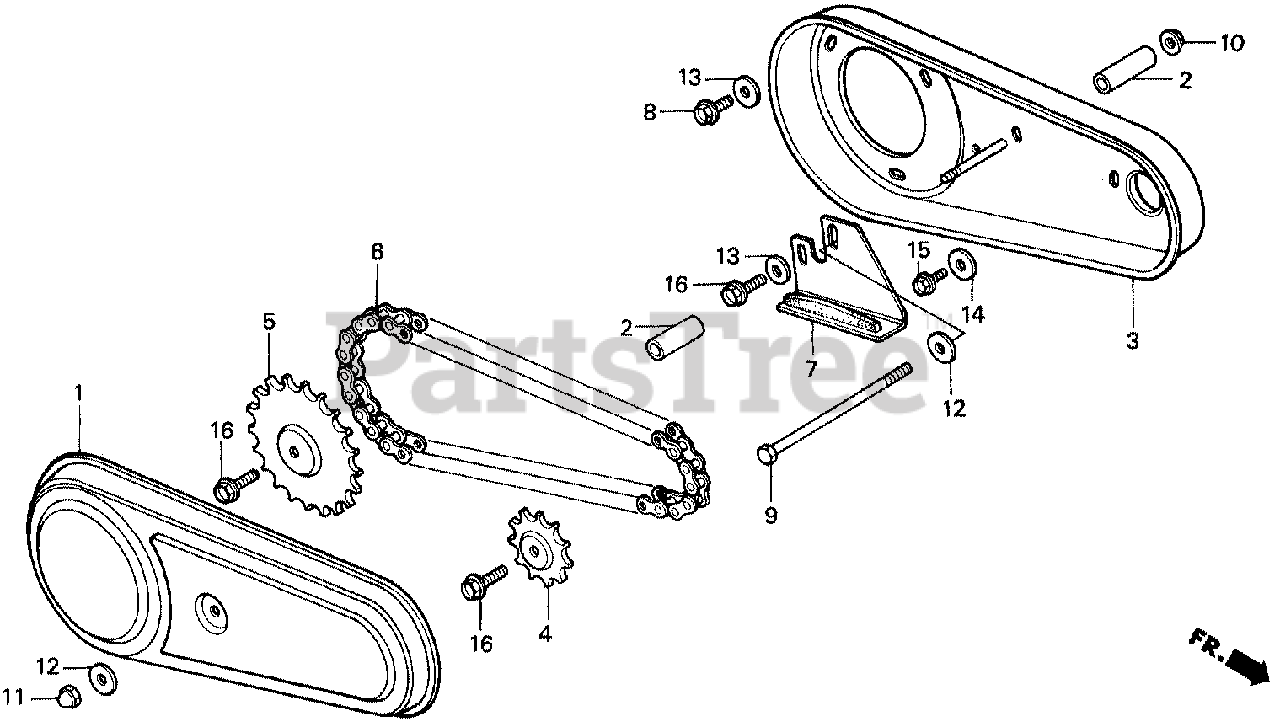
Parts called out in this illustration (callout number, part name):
1	COVER, PRIMARY
2	COLLAR, DISTANCE
3	CASE, PRIMARY
4	SPROCKET, PRIMARY DRIVE (11T) (NOT AVAILABLE)
5	SPROCKET, PRIMARY DRIVEN (22T) (NOT AVAILABLE)
6	CHAIN, PRIMARY
7	TENSIONER, PRIMARY CHAIN
8	BOLT, FLANGE (8MM)
9	BOLT, HEX. (8X115)
10	NUT, FLANGE (8MM)
11	NUT, CAP (8MM)
12	WASHER, PLAIN (8MM)
13	WASHER, PLAIN (8MM)
14	WASHER, PLAIN (6MM)
15	BOLT, FLANGE (6X12)
16	BOLT, FLANGE (8X16)
